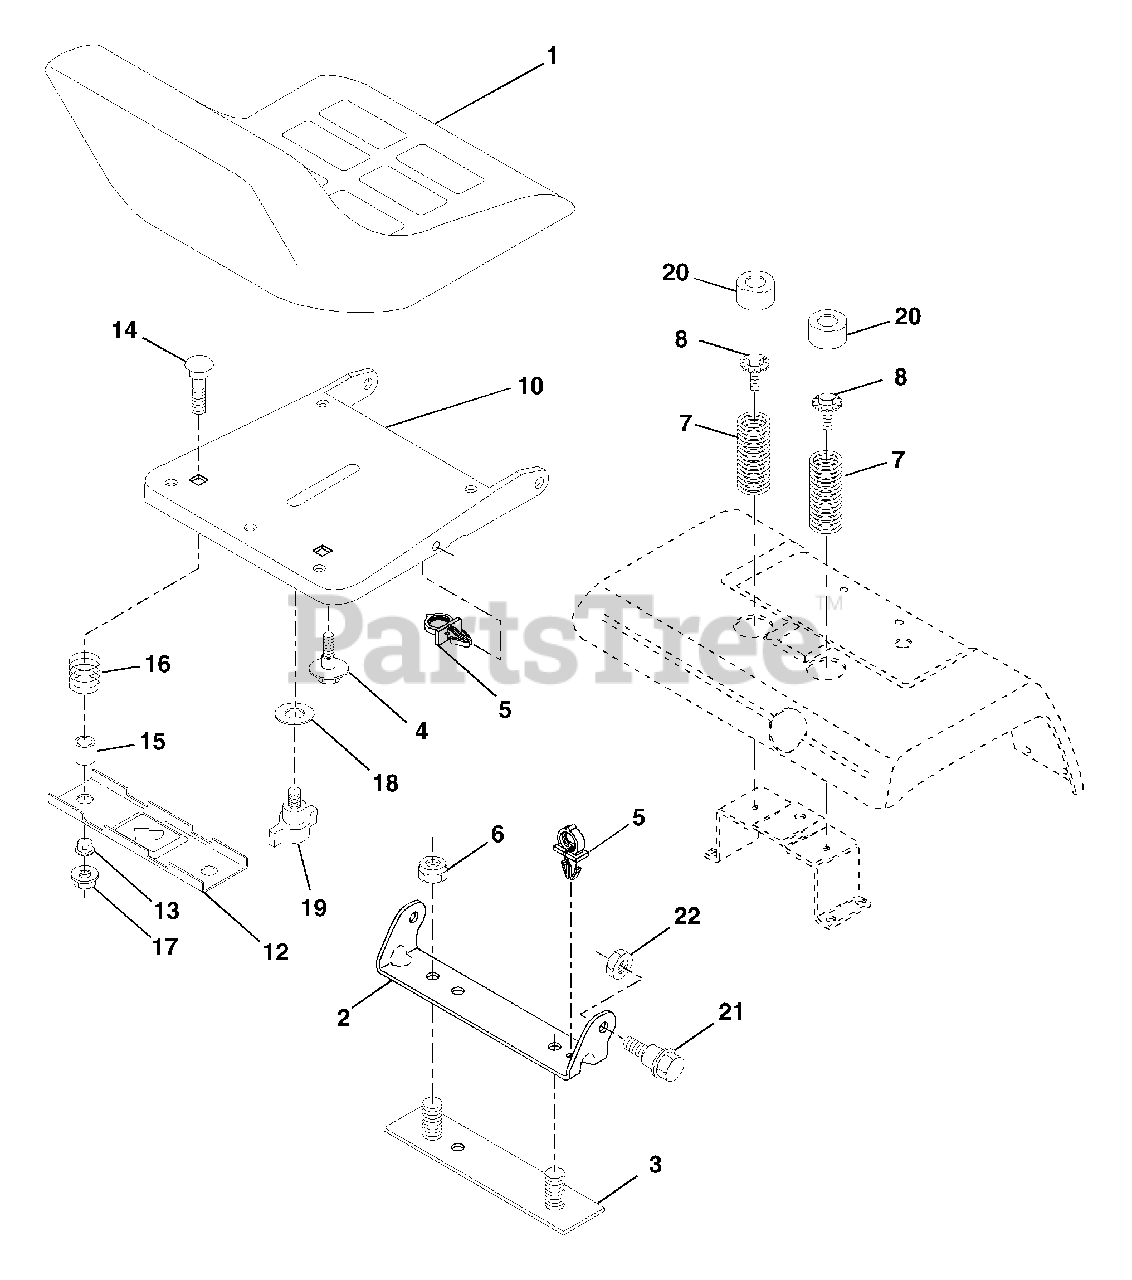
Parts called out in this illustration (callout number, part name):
1	Seat
2	Bracket, Pivot Seat
3	Strap, Fender Asm.
4	Bolt, Shoulder 5/16-18 x .62
5	Clip, Push-In Hinged
6	Nut, Crownlock 3/8-16
7	Spring, Seat Cprsn.
8	Bolt 5/16-18 UNC x 3/4 w/Sems
10	Pan, Seat
12	Bracket, Mounting Switch
13	Bushing, Snap
14	Bolt, Carriage 1/4-20 x 1-1/2
15	Spacer, Split
16	Spring, Cprsn.
17	Nut, Lock 1/4 Lg. Flg. Gr. 5
18	Washer 17/32 x 1-3/16 x 12 Ga.
19	Knob, Seat
20	Cap, Spring Seat Blk
21	Bolt 5/16-18 Unc-2A
22	Nut, Crownlock 5/16-18
